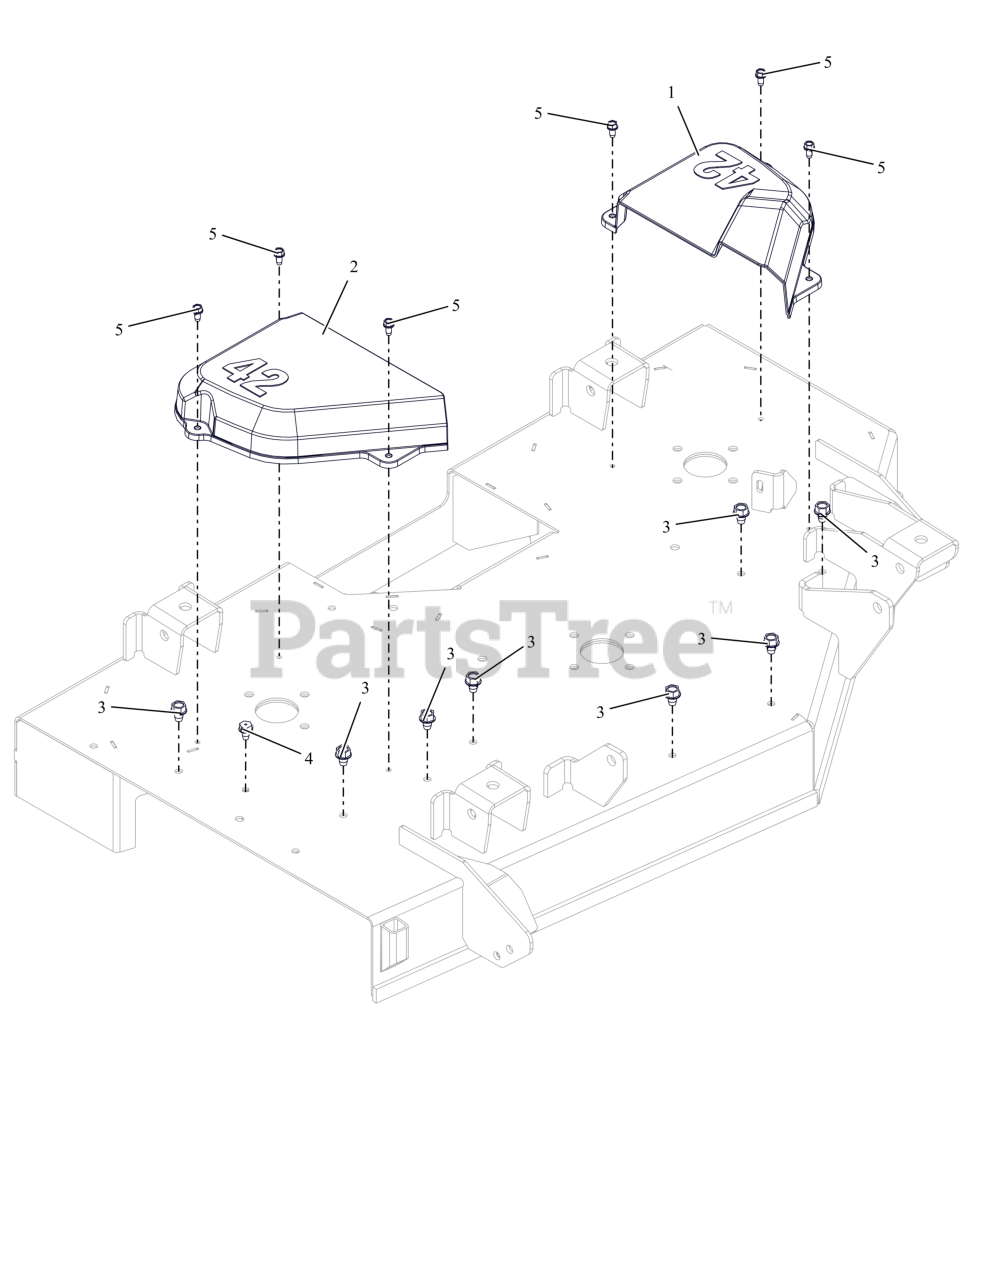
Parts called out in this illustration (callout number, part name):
1	COVER, BELT 42" LH
2	COVER, BELT 42" RH
3	SCR,TAP .375-16X.50 HWH TR ZCC
4	SCR,TAP .312-18X.50 HWH TR ZCC
5	SCR-TAP .25-20X.50 HWH ZCC
